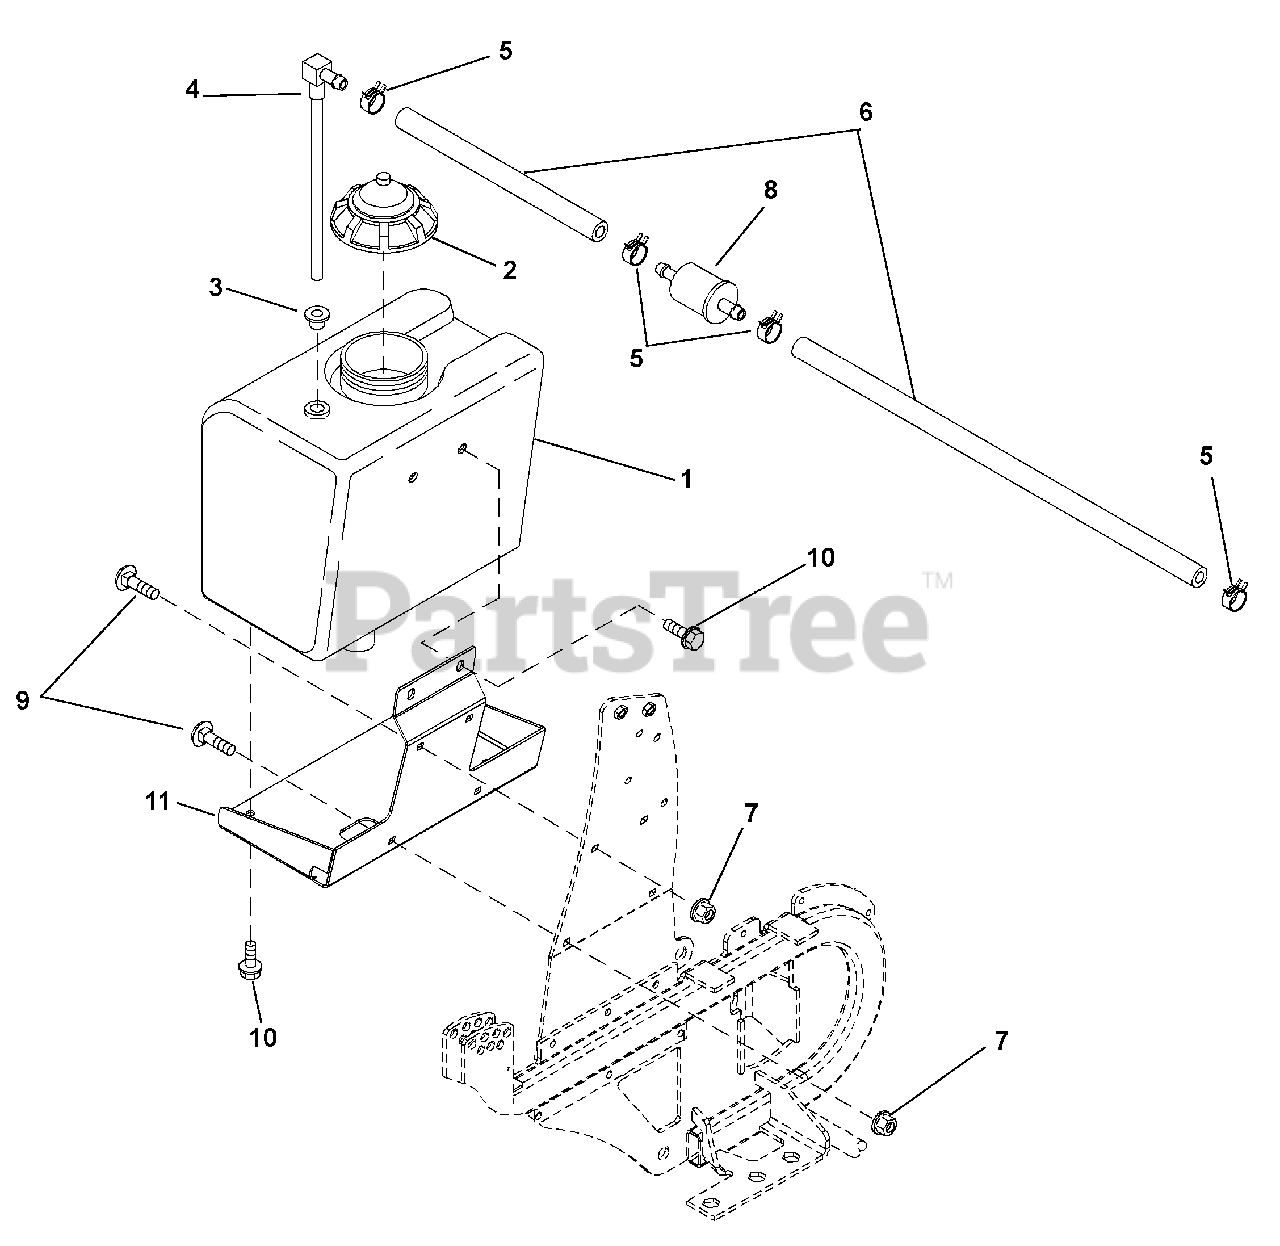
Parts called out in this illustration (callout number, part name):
1	Fuel Tank (includes 2, 3 and 4)
2	Cap, Fuel
3	Grommet
4	Fuel Pickup
6	Hose, 10 FT Service (cut as needed)
7	Nut, Lock, Nylon M10-1.5
8	Fuel Filter, Kawasaki
9	Carriage Bolt, M10 x 1.5 x 25
10	Bolt, Hex, M8 x 1.25 x 16
11	Bracket, Fuel Tank Mounting Welding
